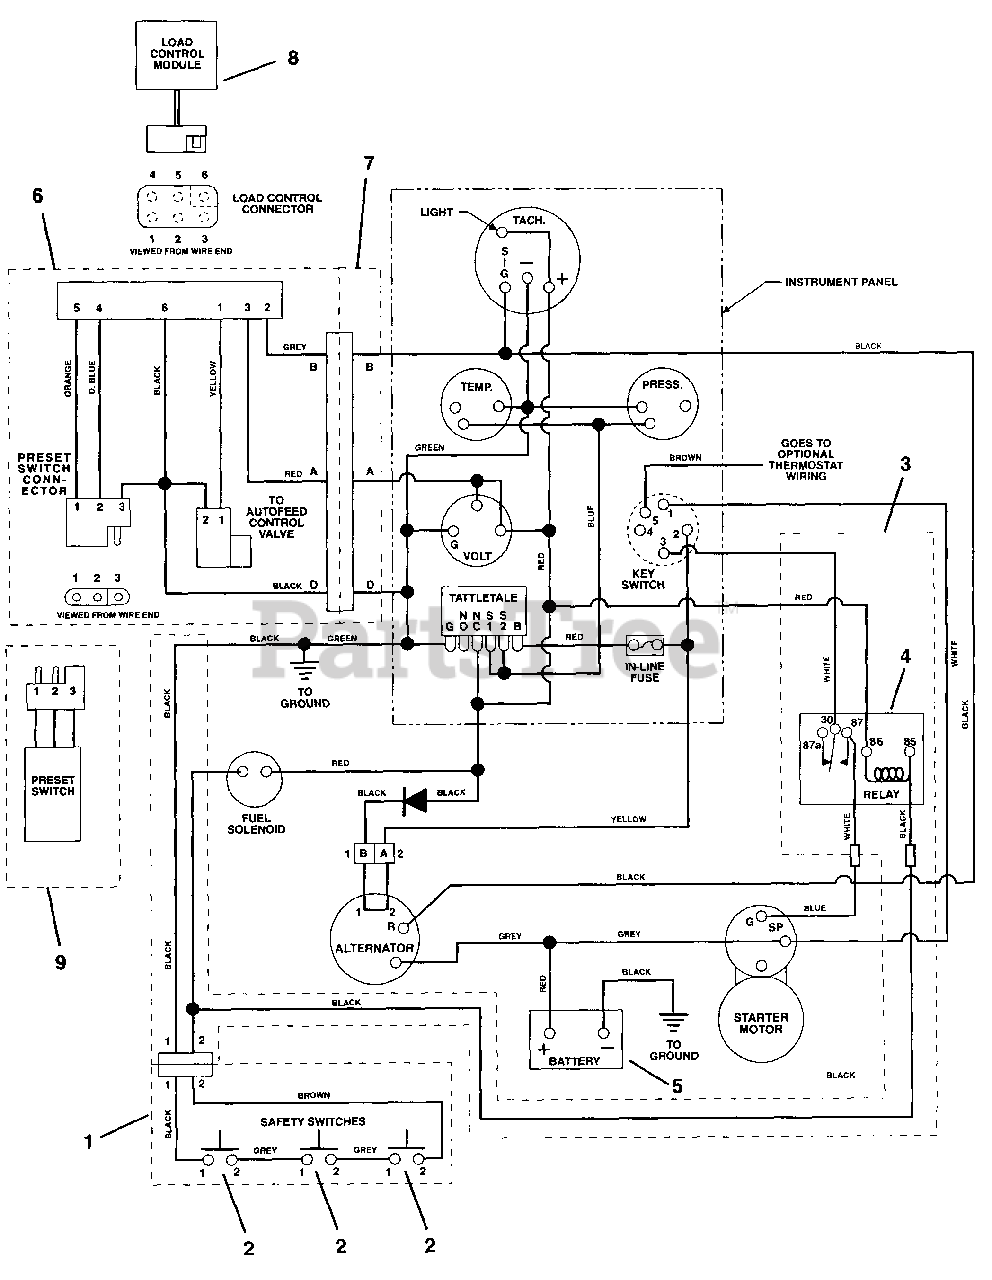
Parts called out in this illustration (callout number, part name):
1	Harness-Wiring, Safety Switch
2	Safety Switch
3	Harness-Relay/Safety
4	Relay
6	Harness-Wiring, 495 Autofeed
6	Harness-Wiring, Autofeed
7	Harness-Adapter, Autofeed
8	Module-Load Control
9	Pre-Set Switch
